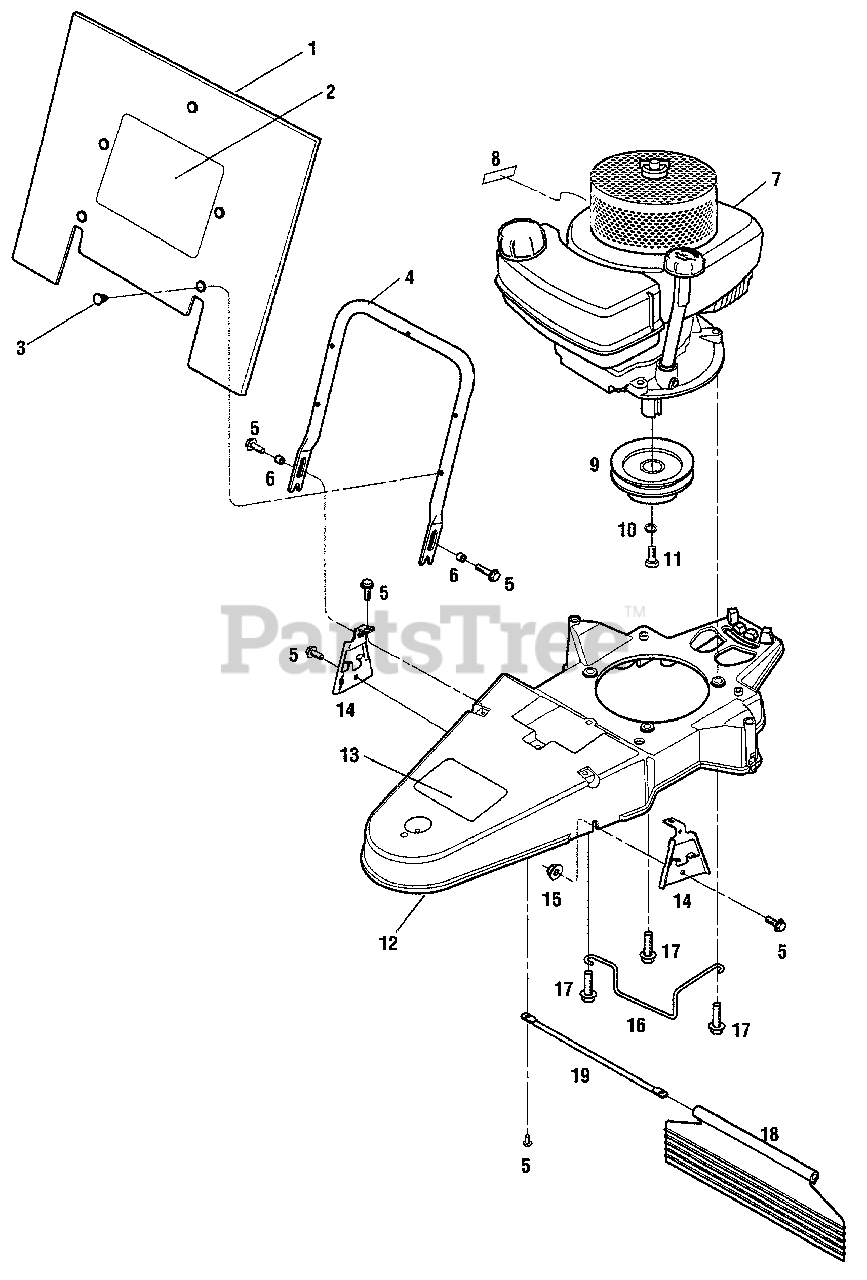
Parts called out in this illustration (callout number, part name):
1	Debris Guard
2	Decal-Logo
3	Push-in Fastener
4	Debris Guard Support
5	Hex Flange Screw, 1/4-20 x 3/4
6	Spacer
7	Engine
8	Decal-Hot Surface Warning
9	Engine Pulley
10	Spring Lock Washer
11	Hex Hd. Screw, 3/8-24 x 1, Grade 5
12	Deck
13	Decal-Warning
14	Hood Bracket
15	Flange Lock Nut, 1/4-20
16	Belt Guide
17	Hex Hd. Screw, 3/8-16 x 1-1/2
18	Deflector Flap
